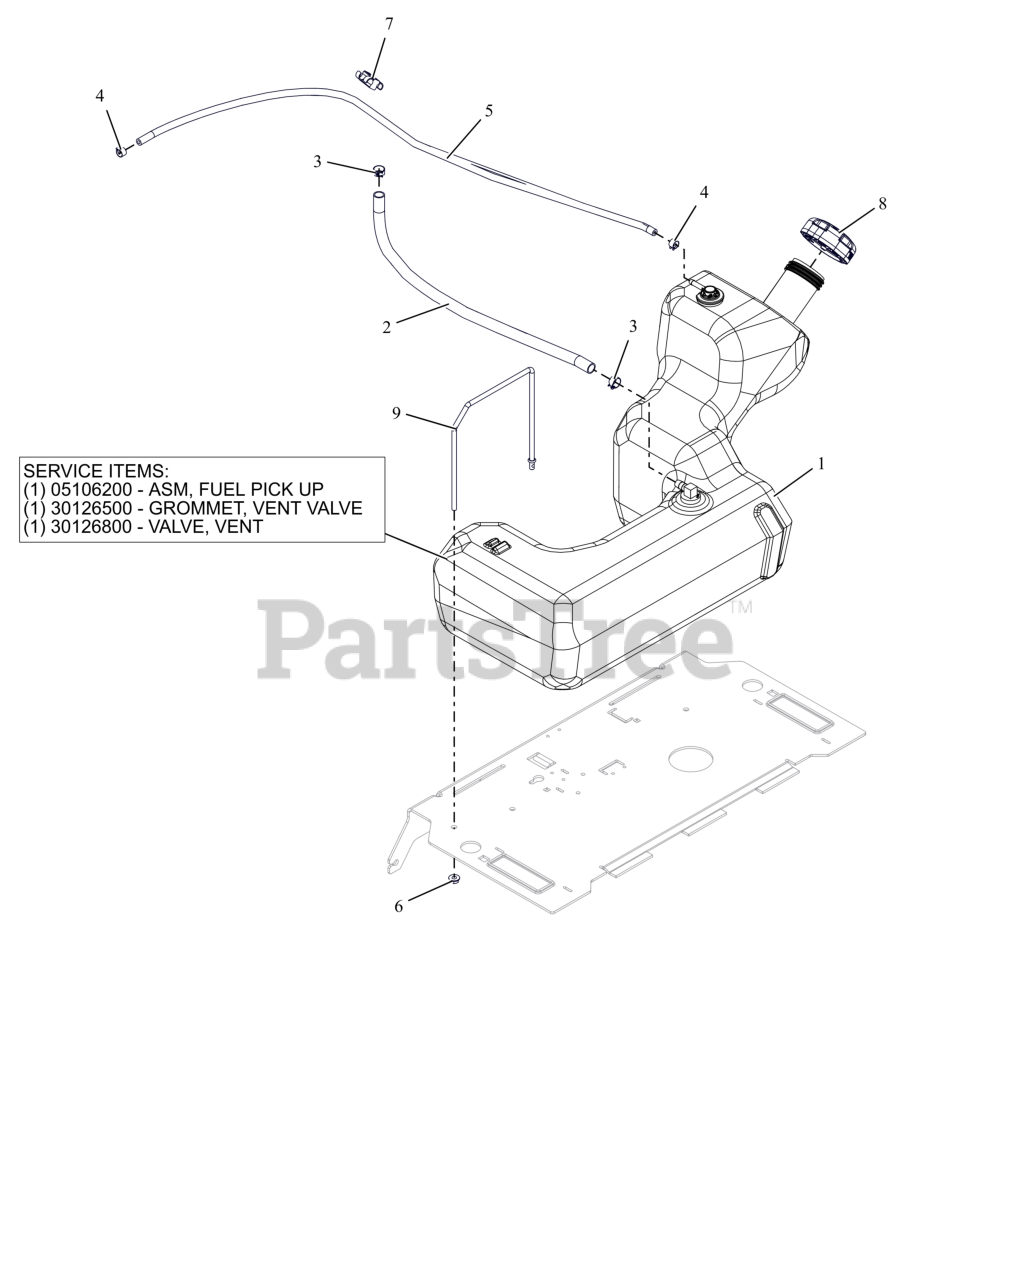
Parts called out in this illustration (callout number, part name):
1	ASM, FUEL TANK - IKON 23
1	ASM, IKON FUEL PICK-UP
1	GROMMET, VENT VALVE
1	VALVE, VENT
1	BSHG-FLG .375X1.062X.625 NITR
2	HOSE, .25 LOW-PERM BULK GAS
3	CLAMP, FUEL LINE
4	CLAMP-HOSE, SPRING .188
5	HOSE, .188 30R7 BULK
6	NUT-LK-CTR-FLG .25-20 ZC120
7	CLIP, T, .38-.50
8	CAP, FUEL - 2.25 RATCHET INLET VENT
9	STRAP- TANK HOLD DOWN
